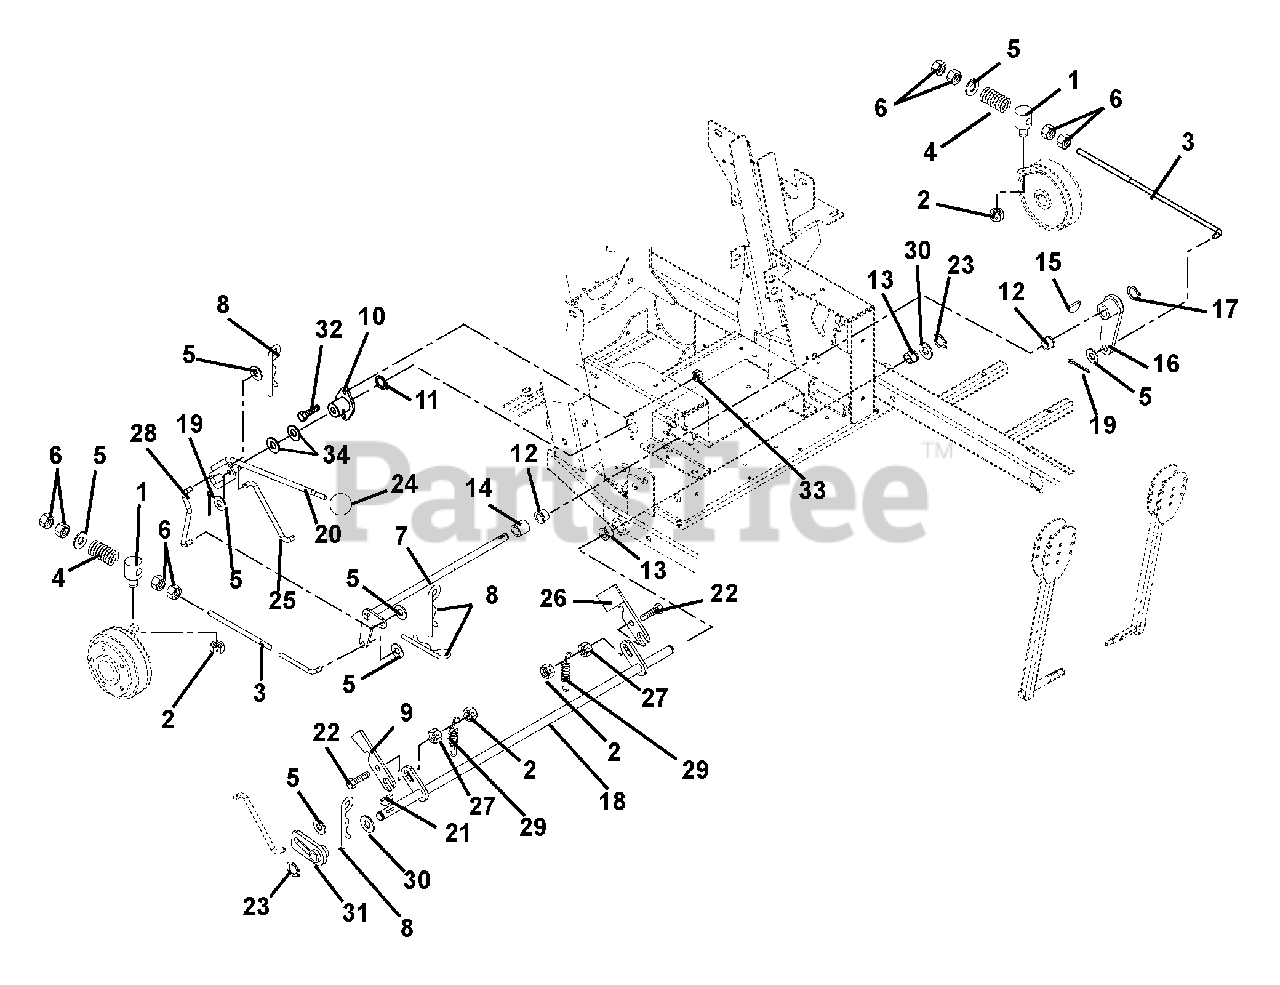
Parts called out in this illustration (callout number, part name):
1	Pivot, Brake Rod
2	Nut, Locking Center .31-18
3	PTO Link Rod
4	Spring, Compression .142 x .710 x 1.75
5	Washer, Flat Steel .406 x .812 x .065
6	Nut, Hex .38-16
7	Shaft, Brake Cross
8	Pin, Hair
9	Slide, Interlocking Brake
10	Bushing, Flange
11	Ring, Retaining External .625 x .05
12	Bushing, Flange Nylon .762 x 1.00 x .58 x 1.48
13	Bushing, Flange .515 x .75 x .745 x 1.00
14	Bushing, Sleeve .75 x 1.00 x .75
15	Key, Woodruff .19 x .75 Hard #9
16	Arm, Brake
17	Ring, Retaining External .69 x .077
18	Weldment, Mechanical Brake
19	Pin, Cotter External .09 x .75
20	Weldment, Brake Actuating
21	Key, Woodruff .13 x .63
22	Bolt, Round Head Square Neck .31-18 x 1.25 Grade 5
23	Ring, Retaining External .50 x .05
24	Knob, Steering Lock
25	Linkage, Brake Actuating
26	Interlock, Safety Switch
27	Nut, Locking Top Flange .31-18
28	Linkage, Brake Actuating
29	Spring, Tension .048 x .44 x 1.75
30	Washer, Flat Steel .505 x 1.00 x .062
31	Weldment, Parking Brake Hub
32	Bolt, Hex .31-18 x .75 Grade 5
33	Nut, Locking Top Flange .31-18
34	Washer, Flat Steel .630 x 1.25 x .062
